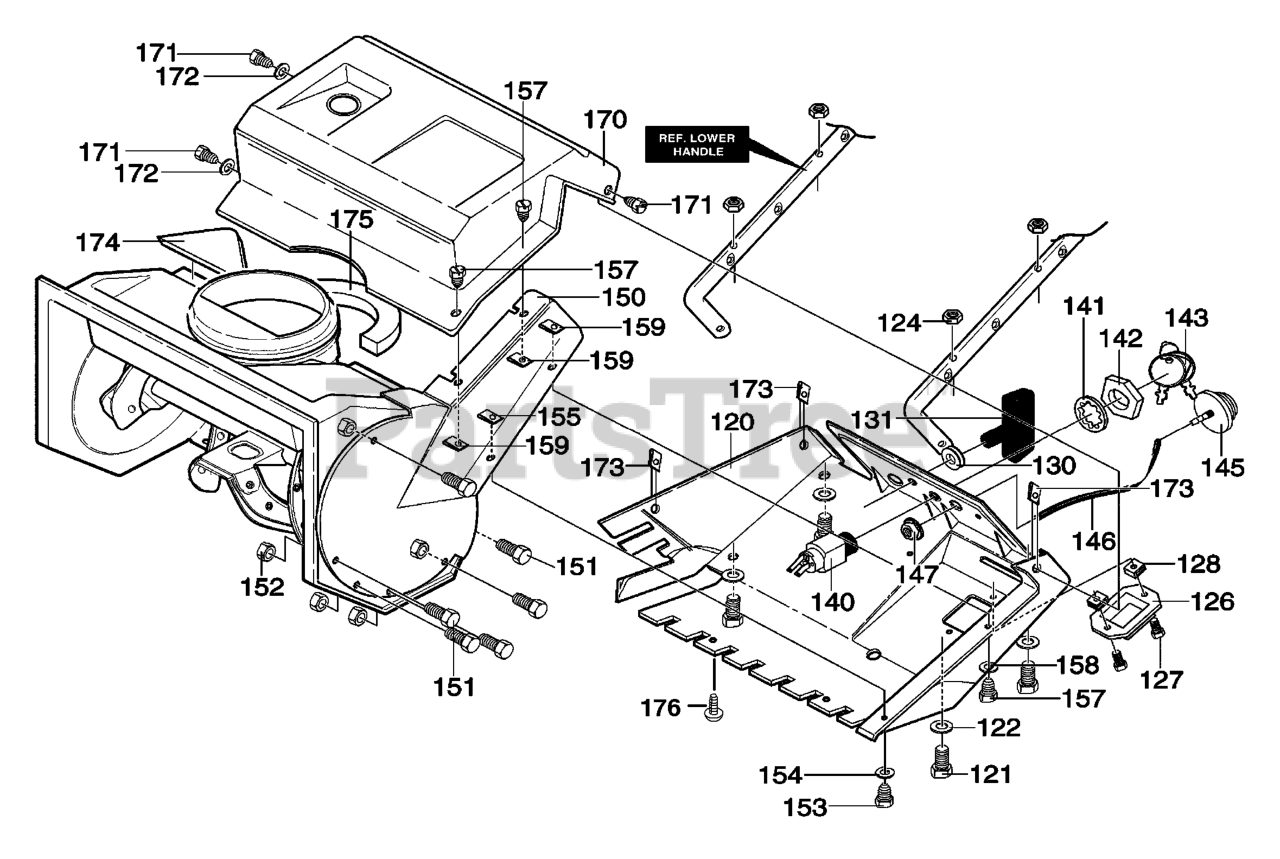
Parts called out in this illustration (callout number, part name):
120	COVER, BOTTOM
121	SCREW, 1/4-20X1.25
122	WASHER, FLAT
124	NUT, 1/4-20
126	PANEL, ACCESS
127	SCREW, 1/4-14X .75
128	NUT, 1/4-10 SPEED
130	GROMMET
140	SWITCH, IGNITION
141	WASHER
142	NUT, 5/8-32
143	2 KEYS & RING
145	PRIMER BULB
146	HOSE, PRIMER
147	NUT, 1/4-20
150	COVER, BELT
151	SCREW, 10-24X .50
152	NUT, #10-24
153	SCREW, 1/4-20X .50
154	WASHER, FLAT
155	NUT, 1/4-10 SPEED
157	SCREW, 1/4-14X .75
158	WASHER, FLAT
159	NUT, 1/4-10 SPEED
170	COVER, TOP
171	SCREW, 1/4-14X .75
172	WASHER, FLAT
173	NUT, 1/4-10 SPEED
